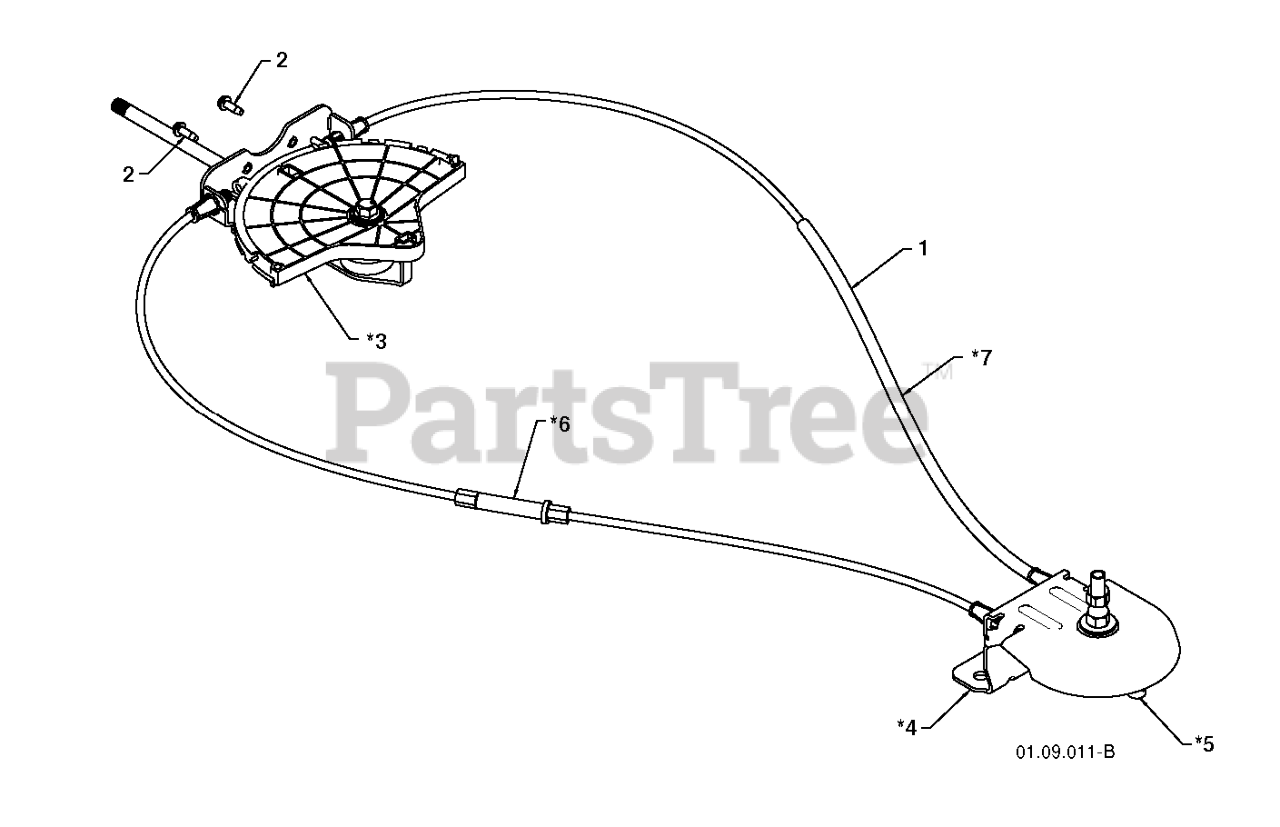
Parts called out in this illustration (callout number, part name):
1	RB LEVER.CABLE.ASM.ROTATR.PLTD
2	SCREW #10-24 X 5/8
3	CHUTE.ROT.HEAD.SERVICE
4	SNOW.PIVOT.BRKT.GRY.SERVICE
5	SNOW.PIVOT.PULLY
6	SNOW.CABLE.ASM.ADJUSTABLE.GRAY
7	SNOW.CABLE.ASM.SERVICE
